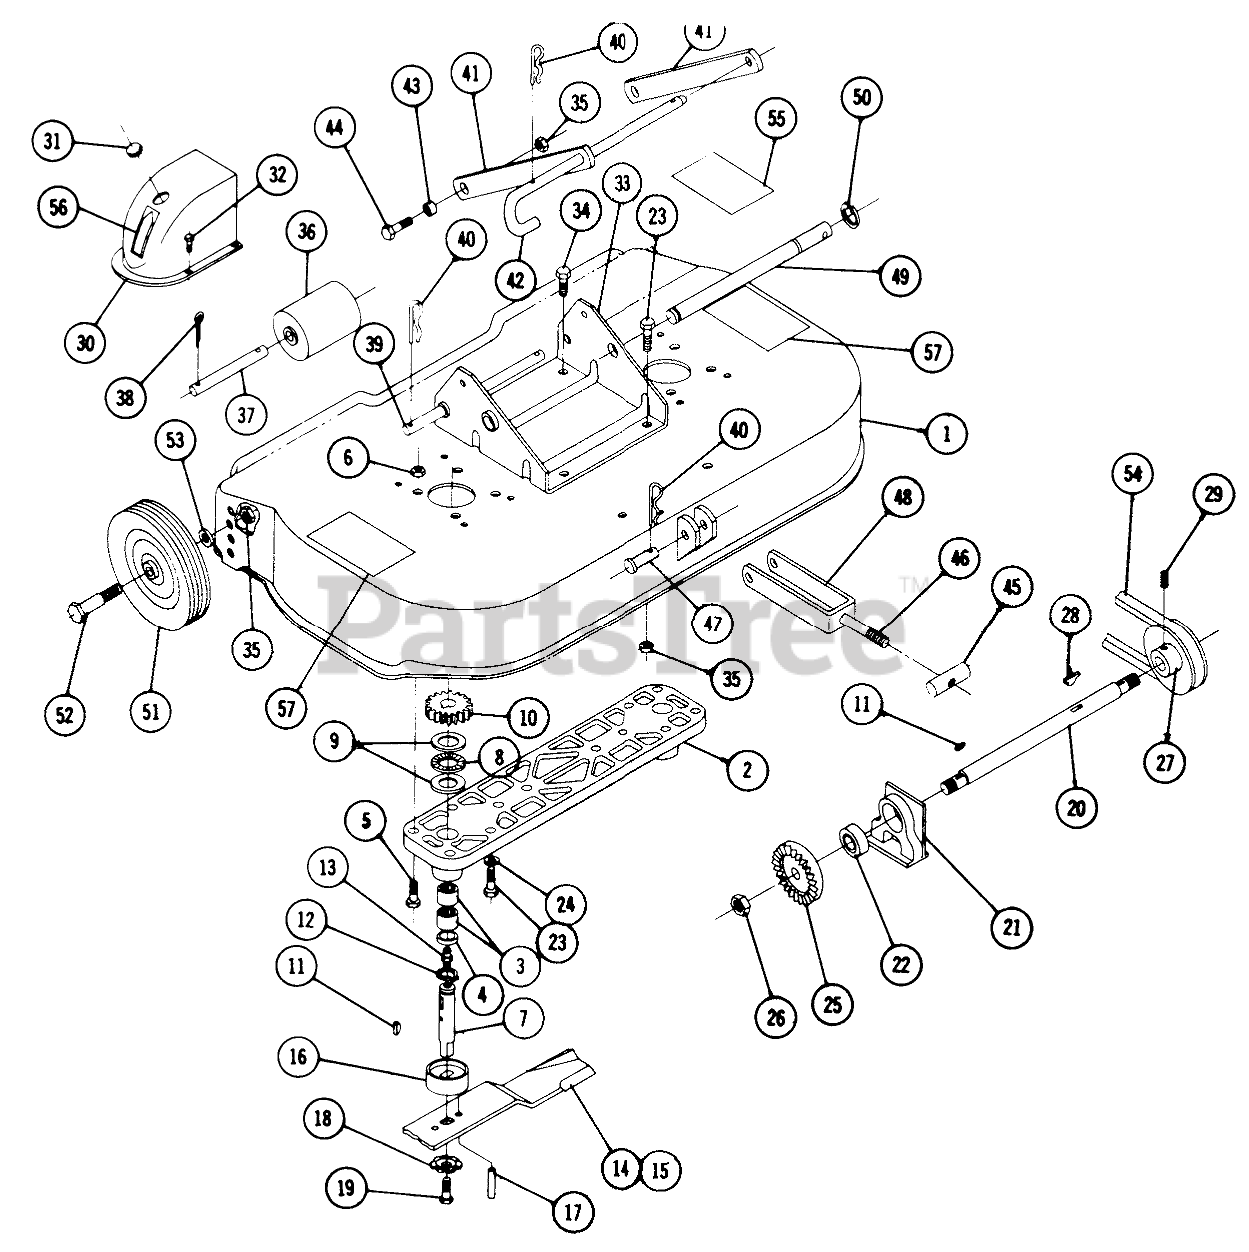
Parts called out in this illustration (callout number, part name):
1	Ass-y. Deck
5	Bolt, 5/16-18 X 7/8
6	Nut-Nylok
9	WASHER-THRUST
11	Ke #5 Woodruff
17	Roll Pin 1/4 x 34
19	Bolt 3/8-16 x 7/8
23	Bolt 3/8-16 x 1
24	Lockwasher
29	Set Screw 5/16 18 x 5/16 Nylok
31	PLUG BUTTON
32	SCREW
33	Hanger
34	Bolt 3/8-16 x 3/4
35	3/8-16 E.S.
38	Cotter Pin
39	Pin
40	Hairpin
44	Bolt 3/8-16 x 7/8
46	Bolt Square Head 1/2-13 x 2 3/4
47	Clevis Pin
48	SPACER CLUTCH ARM
49	Shaft-Belt Tightener
50	E-RING
52	BOLT-SHOULDER
53	Washer
54	V BELT
55	Decal-Belt Diagram
56	Decal
